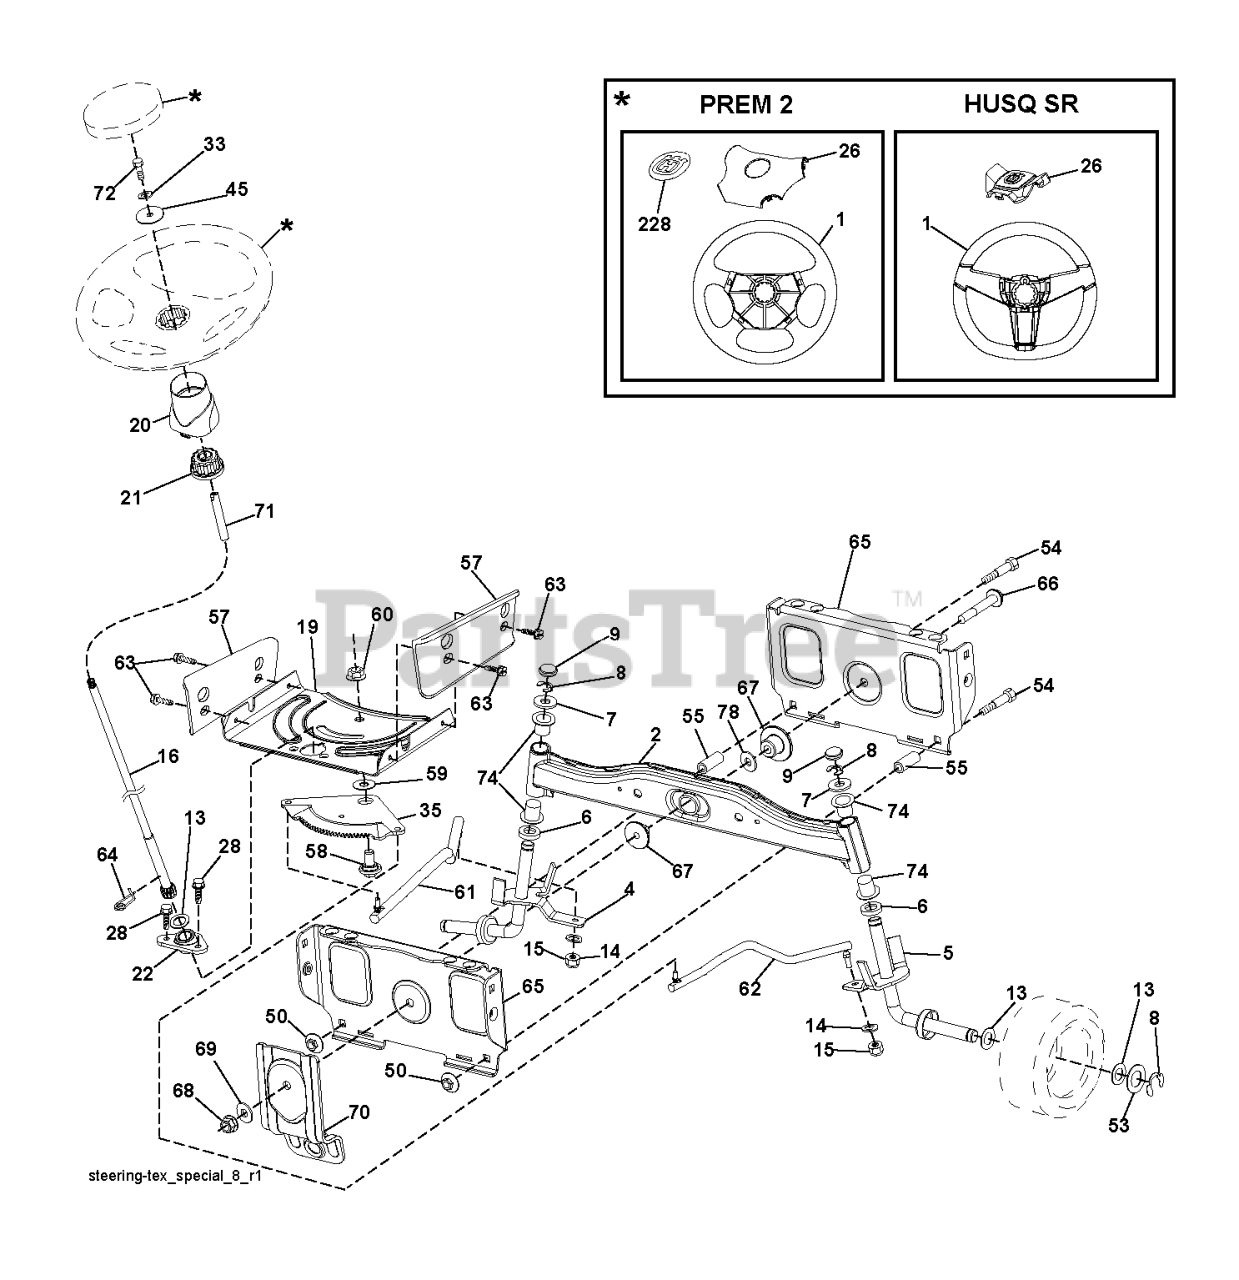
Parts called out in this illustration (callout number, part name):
1	RP WHEEL.STEER.HUSQ.PREM.OVMLD
2	AXLE HALF ASM-WELDED
4	SPINDLE.WELDED.LH.15"TEX
5	SPINDLE.WELDED.RH.15"T
6	THRUST WASHER
9	CAP.SPINDLE.BLACK
14	WASHER, LOCK 3/8
15	NUT CROWNLOCK 3/8-24
16	SHAFT STEERING
19	PLATE.STEER.DDL.NLT/NG
20	BOOT, STEERING
21	ADAPTER, WHEEL STNG..
22	BUSHING.ASM.STEERING.A
26	RP INSERT.CAP.WHL.STRG.HUSQ.
28	SCREW, 3/8-16X3/4
33	WASHER.LOCK.HVY.HLCL.SPR.5/16
35	GEAR.SECTOR.PLATE.DDL.
45	WASHER.11/32
50	NUT LOCK FLG 3/8-16 UNC
53	WASHER.HARDENED
55	SPACER.BRACE.AXLE
57	BRACKET.UPSTOP.TEX
58	BOLT.SHOULDER.SECTOR.P
59	WASHER.THURST.SECTOR.S
60	NUT FLANGE LOCK 5/8-11
61	DRAGLINK.LH.BALLSTUD.D
62	DRAGLINK.RH.BALLSTUD.D
63	SCREW
64	RETAINER.CLIP.SPRING.S
65	BRACE.AXLE.FRONT.NLT/N
66	BOLT HEX FGHD 7/16-14 X 3 SERR
67	BUSHING.PM.FRONT AXLE
68	NUT.LOCK.FLANGE.7/16
69	WASHER.1.5X.505X.118
70	BRKT.DECK.SUSPENSION.F
71	SHAFT EXTENSION STEERING
72	BOLT YT
74	BRNG T
78	THRUST WASHER
228	DECAL.WHEEL.STRG.LGN.H
